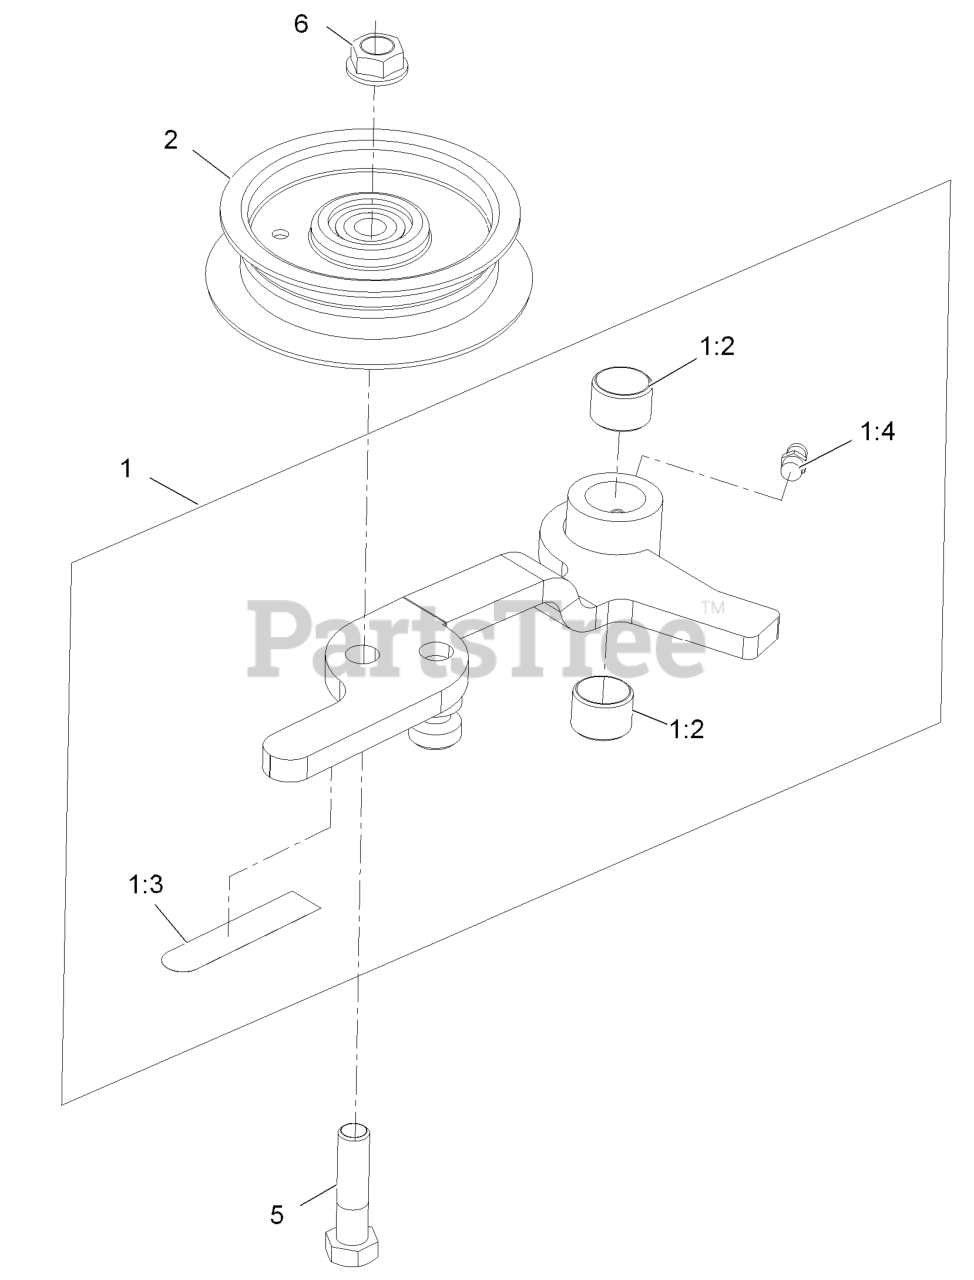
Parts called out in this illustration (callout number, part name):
1	ASM, IDLER ARM - SERVICE
1:2	BUSHING
1:3	DECAL-WARNING
1:4	FITTING-GREASE
2	IDLER-FLAT
5	SCREW-HH
6	NUT-HHF, WHIZ
